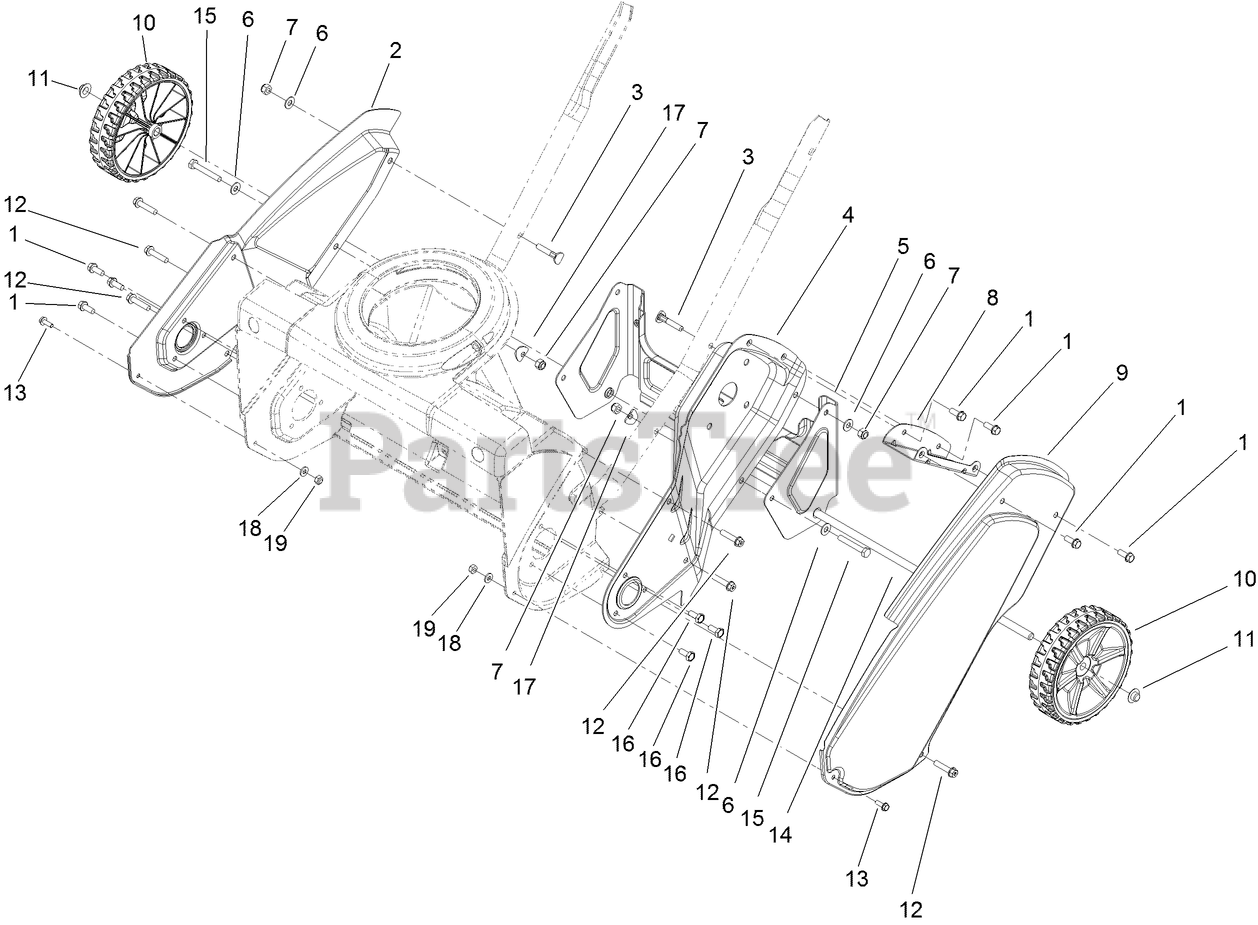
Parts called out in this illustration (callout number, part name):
1	SCREW-HWH
2	SIDEPLATE-RH
3	SCREW-HANDLE
4	SIDEPLATE-LH
5	BRACKET-WHEEL
6	WASHER-FLAT
7	NUT-LOCK, NI
8	BRACKET-COVER, BELT
9	COVER-BELT
10	WHEEL ASM
11	NUT-PUSH
12	SCREW-PLASTIC
15	SCREW-HH
16	SCREW-HH, TAPTITE
17	WASHER
18	WASHER-FLAT
19	NUT-LOCK, NI
